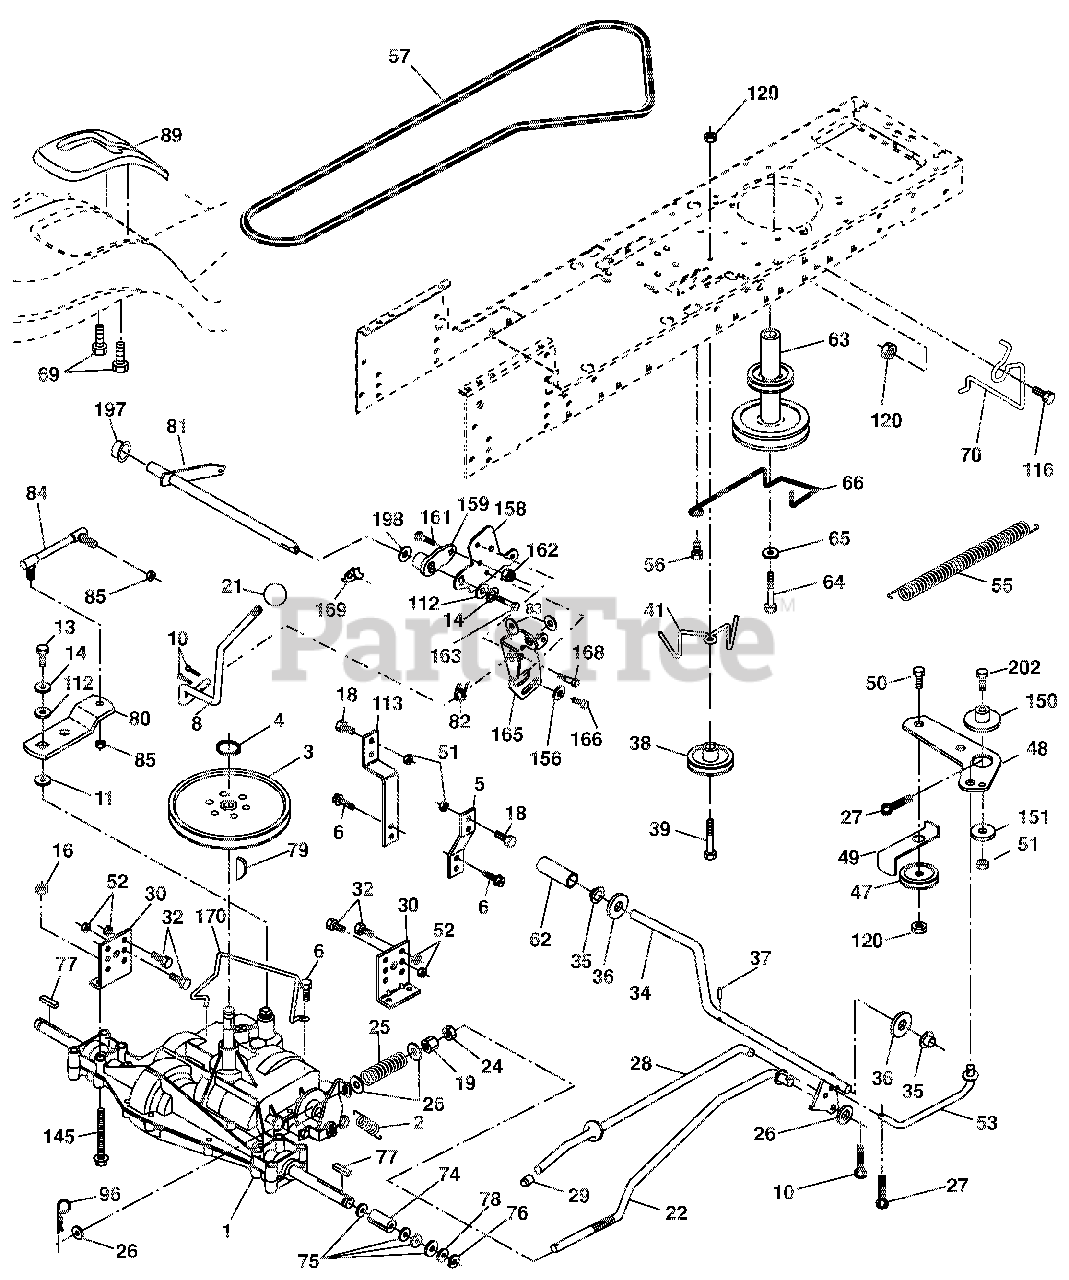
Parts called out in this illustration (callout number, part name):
1	TRANSAXLE PEERLESS 206-545C (165670) (ORDER PARTS FROM TRANSAXLE MANUFACTURER.)
2	Spring Return Brake T/a Zinc
3	PULLEY.TRANSAXLE.18/20"TIRES
4	Ring, Retainer
5	Strap Torque 30 Degrees
6	SCREW.5/16-18X3/4.SMGML.TAP/R
8	Rod Shift Fender Adjust Lt
10	Pin Cotter 1/8 x 1 Cad
11	WASHER.PLATE.SHF..388 SQ.HOLE
13	BOLT.1/4-28 UNF.GR8.W/PATCH
14	Washer, Lock 1/4
16	Locknut, Washer Insert 5/16-18
18	Bolt, Fin Hex 3/8-16 unc x 1
19	Locknut, Washer Insert 3/8-16
22	Rod Brake Blk Zinc 26 840
24	Nut, Hex, Jam 3/8-16
25	Spring Rod Brake 2 00 Zinc
26	WASHER.13/32 X 13/16 X 16 GA.
27	PIN.COTTER.1/8 X 3/4.CAD.
28	Rod Brake Parking LT/YT
29	Cap Brake Parking
30	BRACKET
32	Bolt, Hex Head 5/16-18 x 3/4
34	Shaft Asm Pedal Foot
35	BEARING.NYLON.BLK..629 ID.
36	Washer 21/32 x 1 x 16 Ga.
37	PIN.ROLL.3/16X1
38	Pulley Composite Flat
39	BOLT.RDHD.3/8-16UNC X2-3/4 GR5
41	Keeper Belt Flat Idler
47	Pulley Idler V Groove
48	Bellcrank Asm
49	Retainer Belt Style Spring
50	BOLT.CARR.SH.3/8-16X1-1/2.GR5
51	Nut, Hex, Crownlock 3/8-16
52	Nut, Hex, Crownlock 5/16-18
53	Link Clutch
55	SPRING.RETURN.CLUTCH.6.75
56	Screw 3/8-16 x <
57	V-Belt Ground Drive
62	COVER PEDAL BLK ROUND
63	Engine Pulley
64	BOLT.HEX.7/16-20X4XGR5-1.5THR.
65	WASHER.LOCK.HVY HLCL.SPR.7/16
66	Keeper Belt Engine Foolproof
69	SCREW.HEX.WSH.HI-LO.1/4X1/2UNC
70	Guide Belt Mower Drive RH
74	SPACER.AXLE.HYDRO/PEERLES
75	WASHER.25/32 X 1 1/4 X 16 GA.
76	E-RING.#5133-75
77	KEY.SQUARE.2.0 X .1845/.1865
78	WASHER.25/32 X 1-5/8 X 16GA.
79	KEY.WOODRUFF
80	ARM.SHIFT
81	BRACKET
82	Spring Torsion T/a
83	Washer 17/32 x 3/4 x 16 Ga.
85	NUT.LOCK.CENTER.1/4-28 FNTHD.
89	CONSOLE.SHIFT
96	RETAINER SPRING
112	WASHER.9/32 X 3/4 X 10 GA.
113	Strap Torque LT
116	Bolt, Carriage 3/8-16 x 1
120	Nut, Hex, Flangelock 3/8-16
145	BOLT 5/16-18 X 2 1/2 G.5
150	Spacer Retainer
151	WASHER.13/32 X 2 X 10 GA.
156	Washer Srrted 5/16ID x 1.125
158	BRACKET
159	HUB.SHIFT
161	Bolt Rdhd Sqnk 1/4-20 x 3/4
162	Nut Crownlock 1/4-20 unc
163	Bolt Hex Fin 1/4-20 unc x 1 Gr
165	BRACKET
166	Screw 5/16-18 x 5/8
168	Bolt Shoulder 5/16-18 x .561
169	Plate Fastening
170	Keeper Belt Transaxle Gear
197	Nyliner Snap-In
198	Washer Nyliner
202	BOLT.RDHD.3/8-16UNCX1-3/4.GR5
